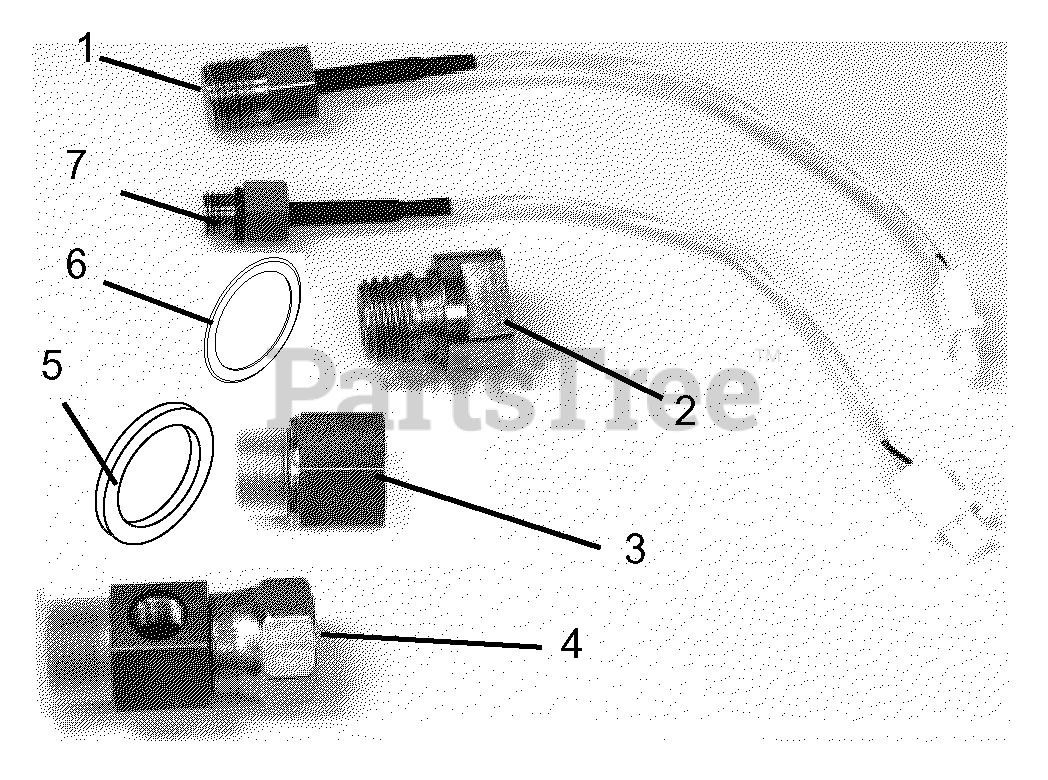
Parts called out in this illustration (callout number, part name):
1	.375 NPT Sensor Harness
2	M20M-.375F ORR/NPTF Adapter
3	M16M-.375F NPTF Adapter
4	8-4 ORFS Hydraulic Sensor Tee Fitting
5	Seal Washer
6	O-Ring
7	.44 UNF Sensor Harness
